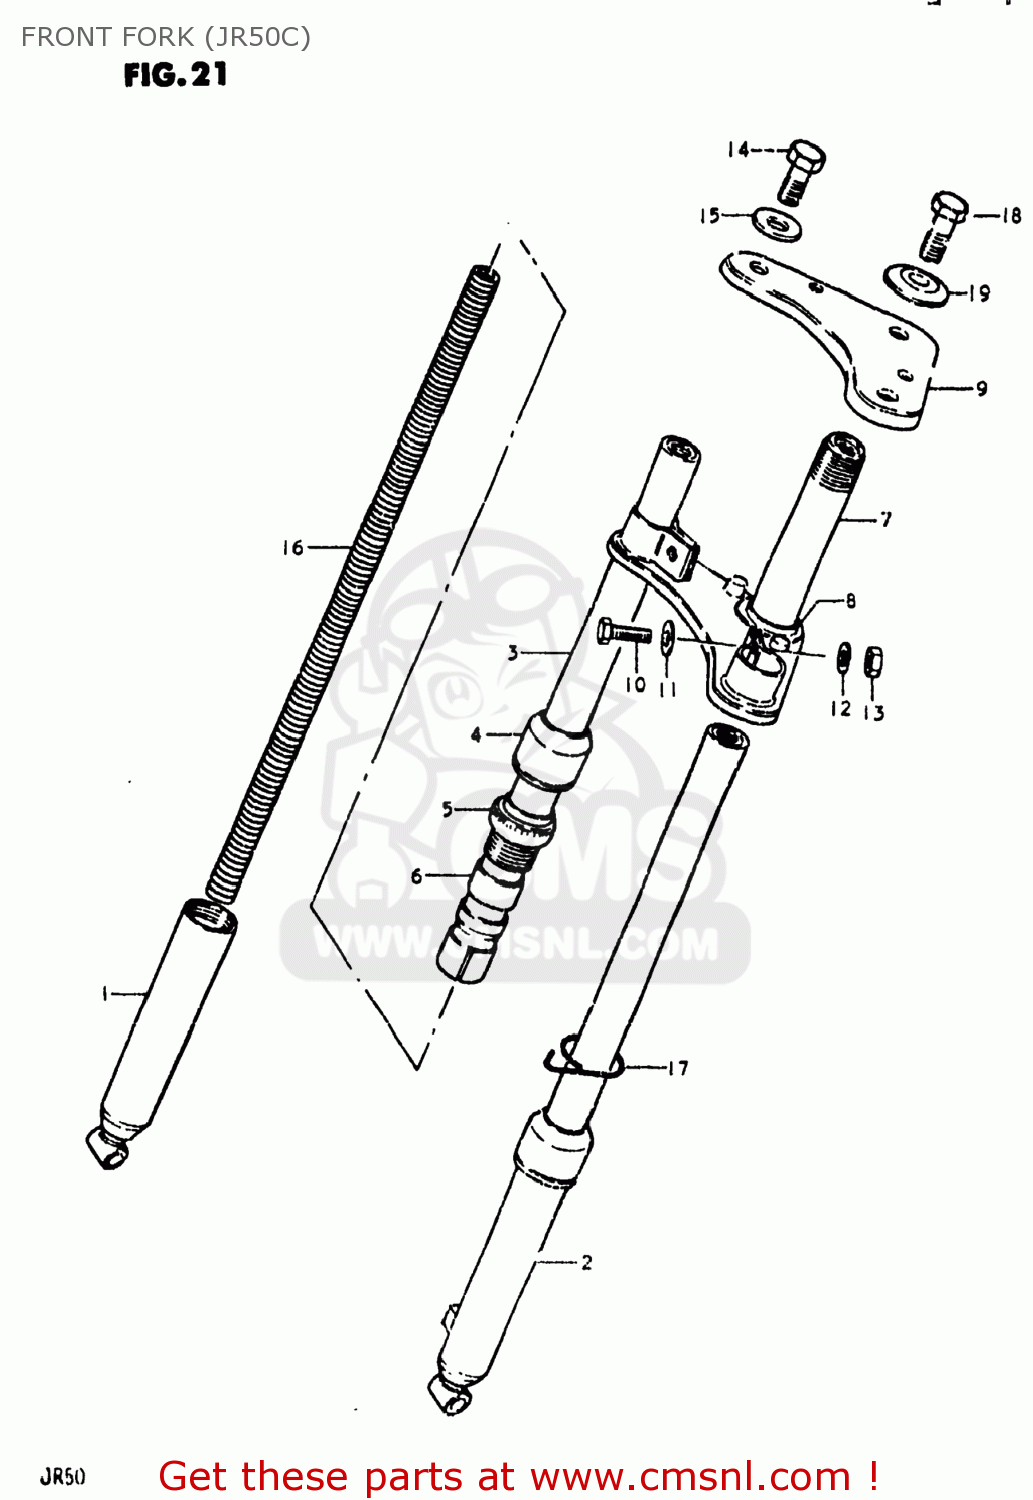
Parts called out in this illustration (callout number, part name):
1	TUBE,OUTER,RIGHT
2	TUBE,OUTER,LEFT
3	TUBE,FORK,INNER
4	SEAL,DUST
5	NUT,OUTER
6	STOPPER
7	STEM,STEERING
8	RACE,STEERING,OUTER,LOWER
9	HEAD,STEERING STEM
10	BOLT, UPPER
11	WASHER 6MM
12	LOCK WASHER
13	NUT
14	BOLT,FRONT FORK,UPPER
15	WASHER,STEERING STEM HEAD
16	SPRING
17	CLIP
18	CAP,FORK INNER TUBE
19	WASHER
